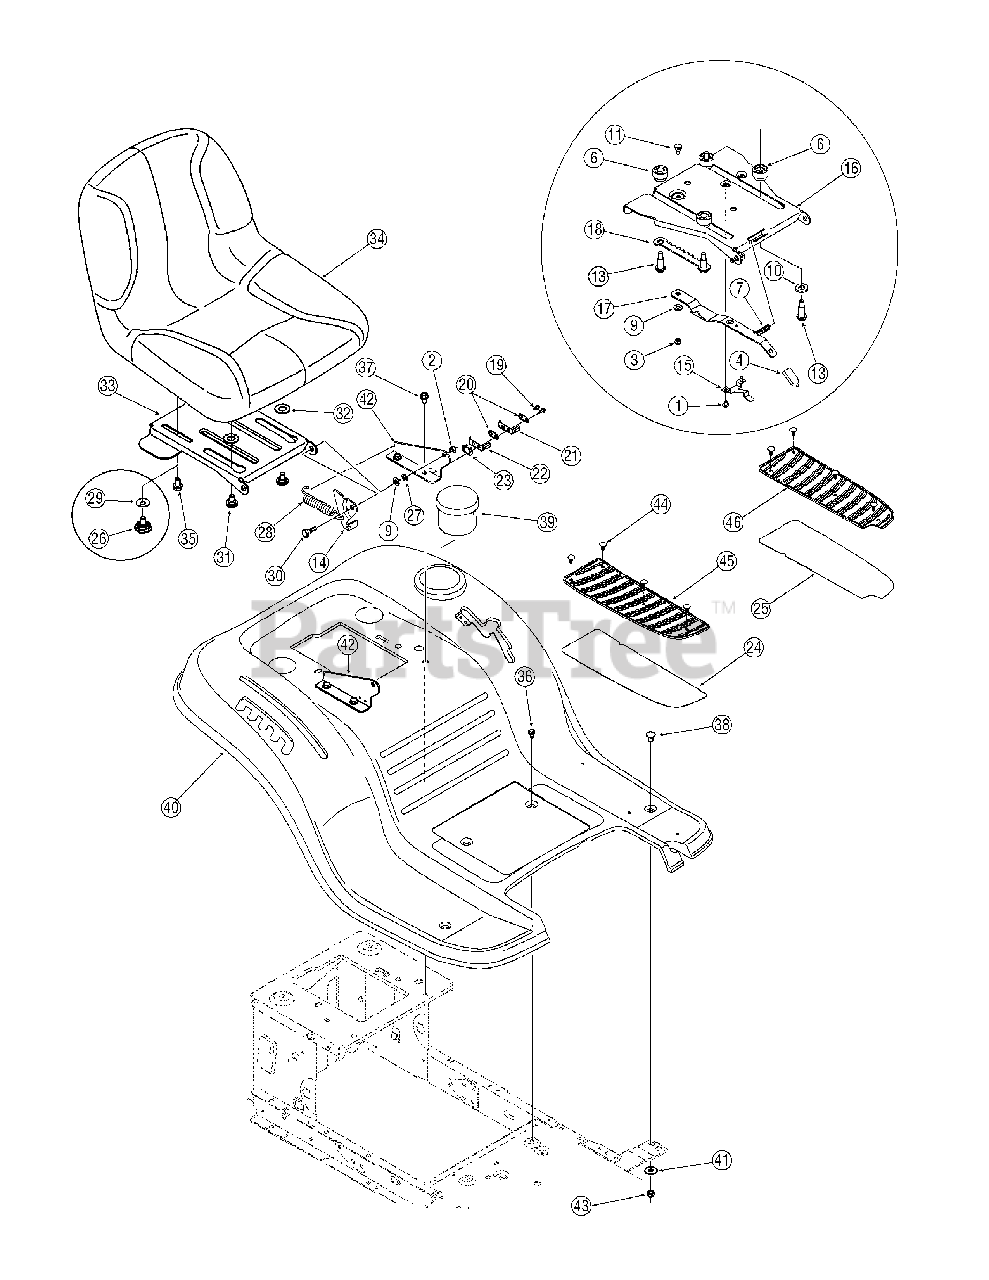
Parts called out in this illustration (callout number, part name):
1	Screw, #10-16, .375
2	Nut, Flange Lock, 5/16-18, GrF, Nylon
3	Nut, Flange Lock, 1/4-20
4	Seat Adjuster Grip
5	Nut, Speed, .3125 ID
6	Spacer
7	Compression Spring, .41 x 1.5
8	Spring, Extension, .84 Dia. x 4.6
9	Wash, Flat, .344 x .688 x .065
10	Wash, Flat, .531x 1.062 x.134
11	Screw, Shoulder, .340 x .285,1/4-20
12	Screw, Shoulder, .437 x .268, 5/16-18
13	Screw, Shoulder, .50 x .925, 3/8-16
14	Seat Bracket, Lift
15	Seat Stop
18	Seat Adjustment Selector
19	Screw, #8-18 x .50
20	Plate, Insulator
21	Spring Switch, Inner
22	Spring Switch, Outer
23	Plate, Insulator Boss
24	Foot Pad, Abrasive, RH
25	Foot Pad, Abrasive, LH
26	Knob, 3/8-16, .625
27	Nut, Speed, .3125 Id
28	Spring, Extension, .84 Dia x 4.6 .
29	Washer, Flat, .406 x 1.00 x .030
30	Screw, Shoulder, .437 x .268, 5/16-18
31	Screw, Shoulder, .625 x .175, 3/8-16
32	Washer. Thrust, .635 x 1.26 x .06
34	Seat, Low Back
34	Seat, Medium Back
35	Screw, 3/8-16, .625
36	Screw, 1/4-20, 0.500
37	Screw, 5/16-12, 0.750
38	Screw, Carriage, 1/4-20, .62 Gr2
39	Cup Holder
41	Washer, Flat, .28 x .74 x .063
43	Nut, Flange Lock, 1/4-20, GrF, Nylon
44	Clip, Ratchet, .250 Dia
45	Foot Pad, RH
46	Foot Pad, LH
